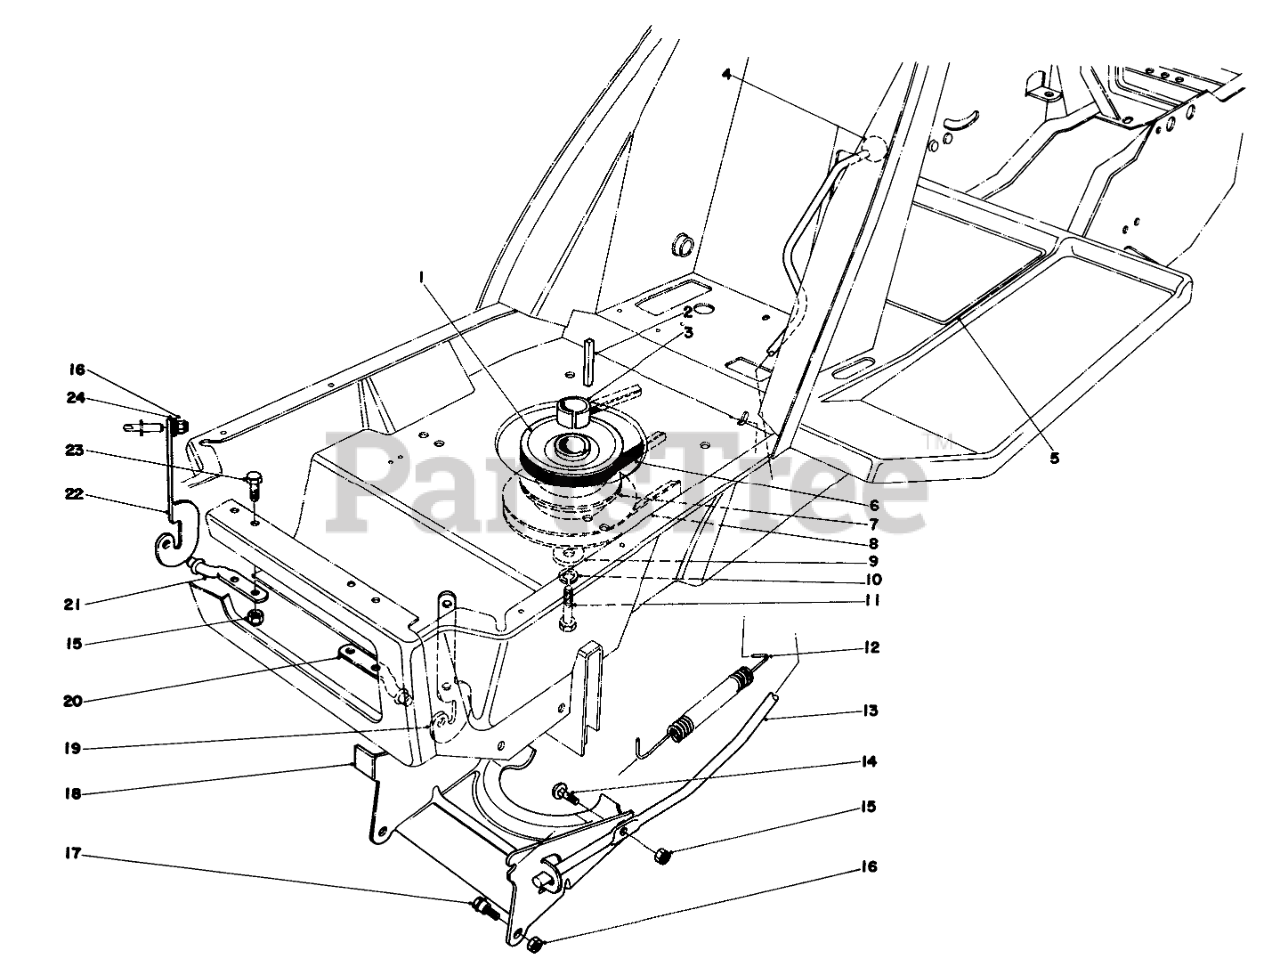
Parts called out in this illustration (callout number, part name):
1	TOP SHEAVE
2	KEY-SQUARE
3	PULLEY SPACER
5	Decal Instruction
6	V BELT
7	Clutch & Brake Deck
8	V BELT
9	WASHER
10	WASHER-LOCK
11	SCREW-HH
12	TRACTION SPRING
13	Engagement Lever
14	Bolt
15	NUT-LOCK, CONE
16	NUT-LOCK, CONE
17	SCREW-SHOULDER
18	CLUTCH ACTUATOR R
19	L.H. HINGE BRACKET
20	LH HOOD HINGE PIN
21	RH HOOD HINGE PIN
22	RH HINGE BRKT
23	SCREW-HH
24	SCREEN SUPT BRKT
